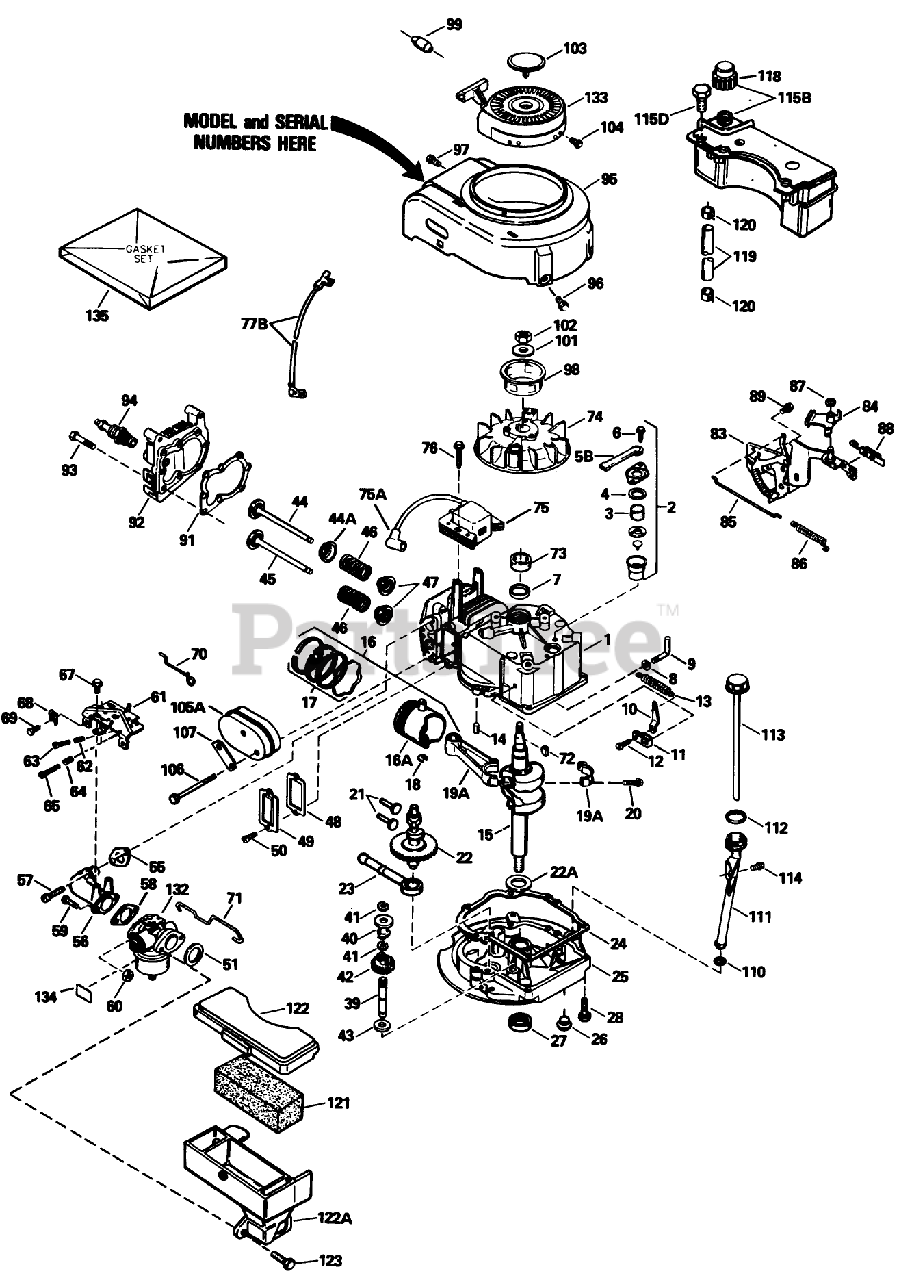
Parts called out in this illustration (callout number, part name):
1	Cylinder Assembly (Incl. Ref. #7 14)
2	Breather Assy. (Incl. Ref. #46 thru 51)
3	Element-Breather
4	Gasket-Breather
5B	Tube, Breaker
6	Screw (10-24 x 9/16)
7	Seal-Oil
8	Washer-Flat
9	Rod, Governor (Incl. No. 36)
10	Governor Lever
11	Clamp-Lever, Governor
12	Screw
13	Spring Governor
14	Pin-Dowel
15	Crankshaft Assy.
16	Piston-Pin Ring Assy. (Std.)(Incl. Ref. #16A, 17 18)
16	Piston-Pin Ring Assembly (.010 oversize)(Incl. Ref. #16A, 17 18)
16	Piston, Pin Ring Assy. (.020 Oversize)(Incl. Ref. #13A, 14, 15)
16A	Piston Pin Assy. (Std.)(Incl. Ref. #14)
16A	Piston Pin Assembly (.010 oversize)(Incl. Ref. #18)
16A	Piston Pin Assy. (.020 Oversize) (Incl. Ref. #14)
17	Ring Set-Piston (Std.)
17	Ring Set, Piston(.0100versize)
17	Ring Set (.020" OS)
18	Ring-Retaining, Piston Pin
19A	Rod Assembly, Connecting (Incl. Nos. 17 18)
20	Bolt-Rod, Connecting
21	Lifter-Valve
22	Camshaft(Mech.Comp. Release)
22A	Washer-Thrust
23	Oil Pump ASM
24	Gasket
25	Flange-Mounting (Incl. Ref. #26, 27 39)
26	Plug Oil Drain
27	Seal-Oil
28	Screw (1/4-20 x 1-1/4)
39	Shaft-Governor
40	Spool-Governor
41	Ring-Retaining
42	Governor Gear ASM
43	Washer
44	Valve, Intake (Std.) (Incl. Ref. #40)
44	Valve, Intake (1/32" oversize)(Incl. No. 40)
44A	Seal Assy., Intake
45	Valve, Exhaust (Std.)(Incl. No. 40)
45	Valve, Intake (1/32" oversize)(Incl. No. 40)
46	Spring-Valve
47	Cap-Valve, Spring
48	Gasket-Cover, Valve
49	Cover-Valve
50	Screw
51	Gasket-Cleaner, Air
55	Gasket-Intake Pipe
56	Pipe-Intake (Incl. Ref. #59)
57	Screw (1/4-20 x 1)
58	Gasket
60	Nut and Lock Washer (1/4-28)
61	Control Assy.-Remote Speed (Incl. Ref. #69 thru 72 76)
62	61709/GIL1515A/95-5
63	Screw
64	Spring-Compression
65	Screw
67	Screw (10-24 x 9/16)
68	Conduit
69	Screw (10-32 x 3/8)
70	2035A67 ADD.ASSEMBL
71	Link-Throttle
72	Key-Flywheel
73	Spacer
74	Flywheel
75	Solid State
75A	Cover-Spark Plug
76	Screw
77B	Ground Wire
83	Bracket-S.E. Brake
84	Lever-Brake
85	Link-Control
86	Spring-Extension
87	Ring-Retaining
88	Terminal
89	Screw (1/4-20 x 3/8)
91	Gasket-Cylinder Head
92	Head-Cylinder
93	Screw (5/16-18x1-1/2)
94	Spark Plug-Resistor (R J19 L M)
95	Housing-Blower
96	Screw (1/4-20 x 1/2)
97	Screw (10-24 x 9/16)
98	Hub-Starter
99	Retainer-Starter Rope
101	Washer-Belleville
102	Nut-Flywheel
103	Plug Starter
104	Screw, Hex Hd.
105A	Muffler
106	Screw
107	Plate-Lock
110	Gasket
111	Oil Fill Tube
112	O-Ring
113	Dipstick
114	Screw (10-32 x 1/2)
115B	Tank Assembly-Fuel (Incl. Ref. #102)
115D	Screw (10-32 x 35/64)
118	Cap-Fuel
119	Line-Fuel
120	Clamp-Line, Fuel
121	Filter-Air Cleaner
122	Cover-Air Cleaner
122A	Body Air cleaner
123	Screw
132	Carburetor (Incl. Ref. #58)
133	Starter-Rewind
134	Decal-Primer
135	Gasket Set (Incl. Items Marked *)
